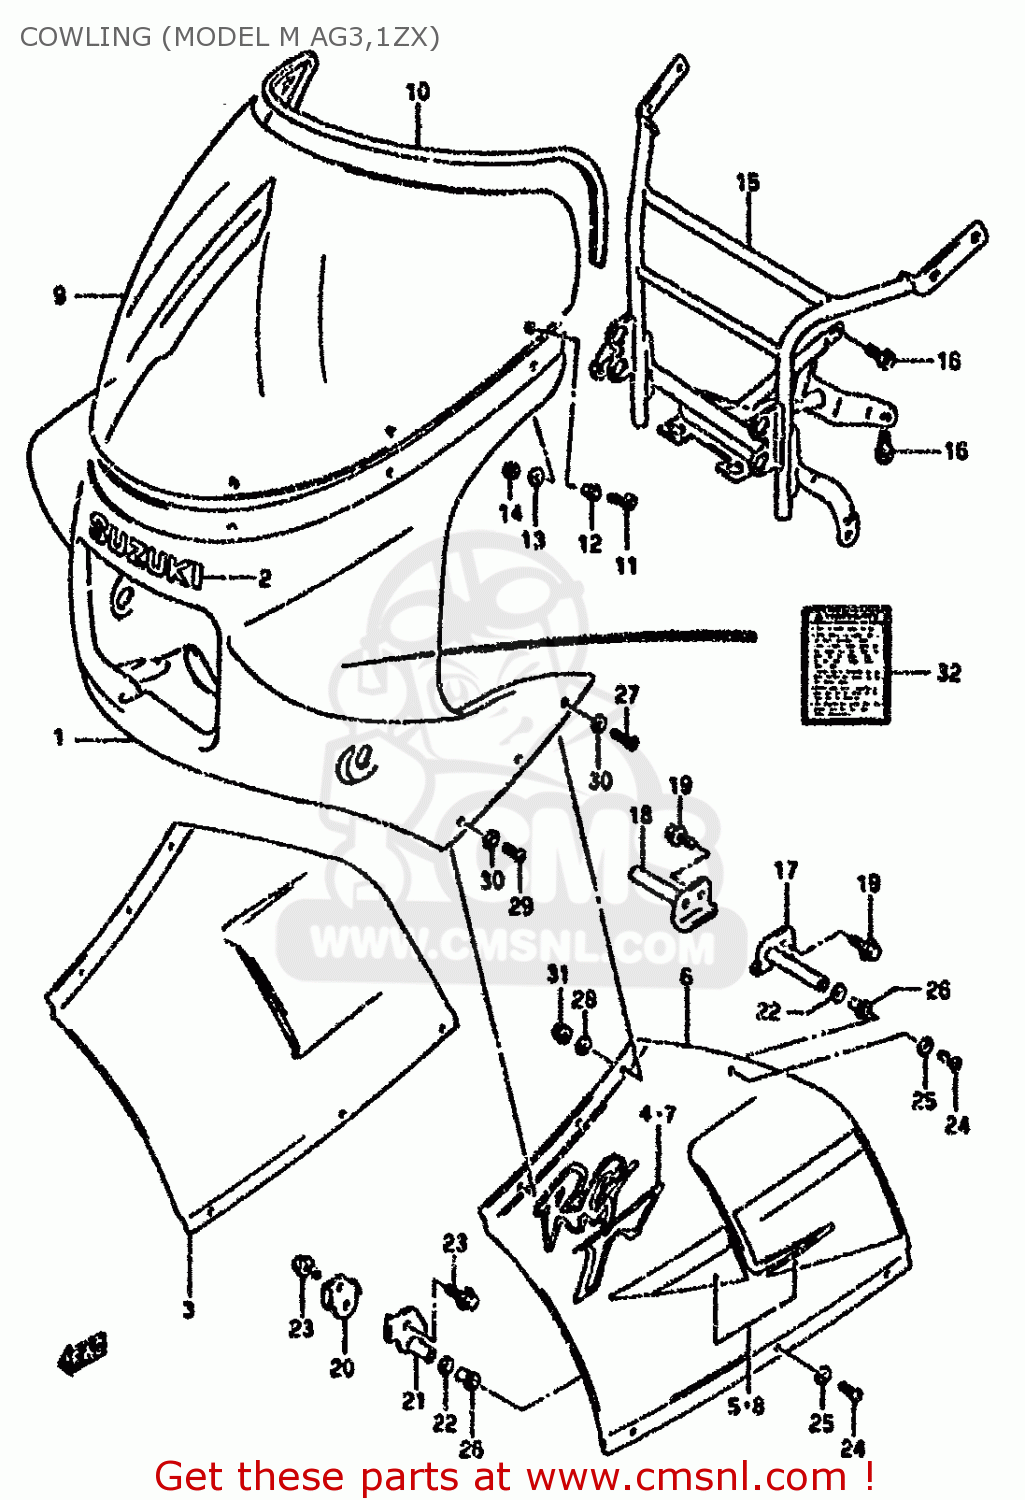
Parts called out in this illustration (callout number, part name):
1	BODY,COWLIG (BLACK)
2	EMBLEM,COWLING UPR
3	COVER,COWL SIDE RH (BLACK)
4	EMBLEM,RG
5	TAPE SET,SIDE RH
6	COVER,COWL SIDE LH (BLACK)
7	EMBLEM,RG
8	TAPE SET,SIDE LH
9	WIND SCREE,COWLING
10	MOLDING, SCREEN
11	SCREW(5X14)
12	CUSHION
13	WASHER
14	NUT 8MM
15	BRACE,COWLING
16	BOLT MAGNETO S
17	BRACE,COWLING RR
18	BRACE,REAR RH
19	BOLT
20	BRACE,SIDE RH
21	BRACE,SIDE LH
22	WASHER (10.5X18X1)
23	BOLT
24	SCREW
25	WASHER(5.2X11X1)
26	NUT
27	SCREW
28	WASHER (6.5X20X1.2)
29	SCREW
30	WASHER(6.5X13X1)
31	NUT
32	LABEL (WARNING,SCREEN)
39	BOLT 6X16
40	SCREW
41	WASHER
42	NUT
43	NUT
44	NUT
45	NUT
